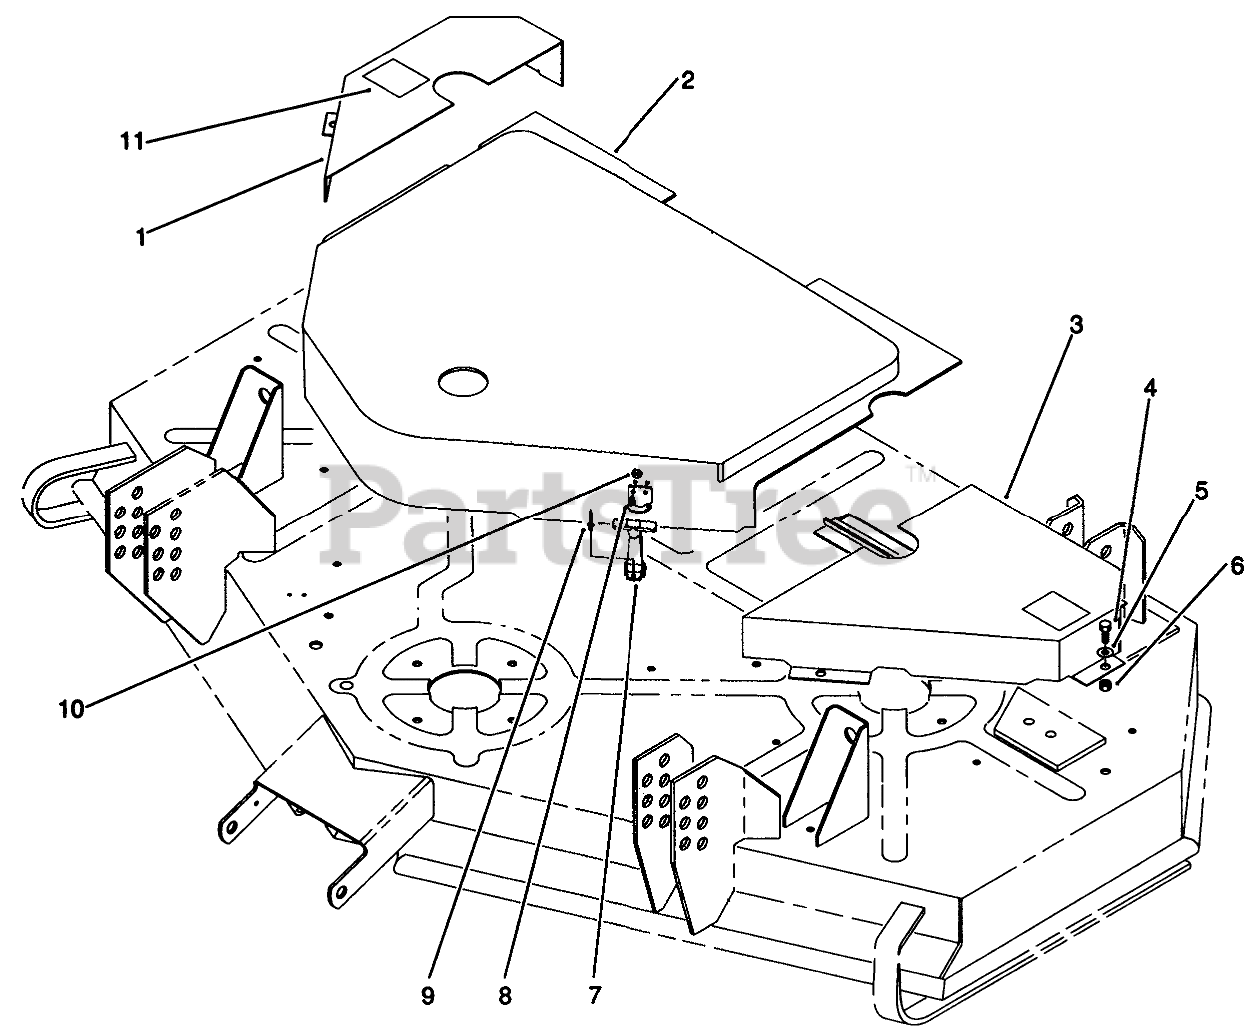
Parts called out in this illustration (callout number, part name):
1	R/H BELT COVER B
2	COVER
3	L/H DECK COVER B
4	1/4-20 X 5/8 CAPSCREW
5	WASHER-FLAT
6	INSERT-THREADED
7	FLEX DRAW LATCH ASM
9	RIVET-POP
10	WASHER
11	DECAL-NO STEP
